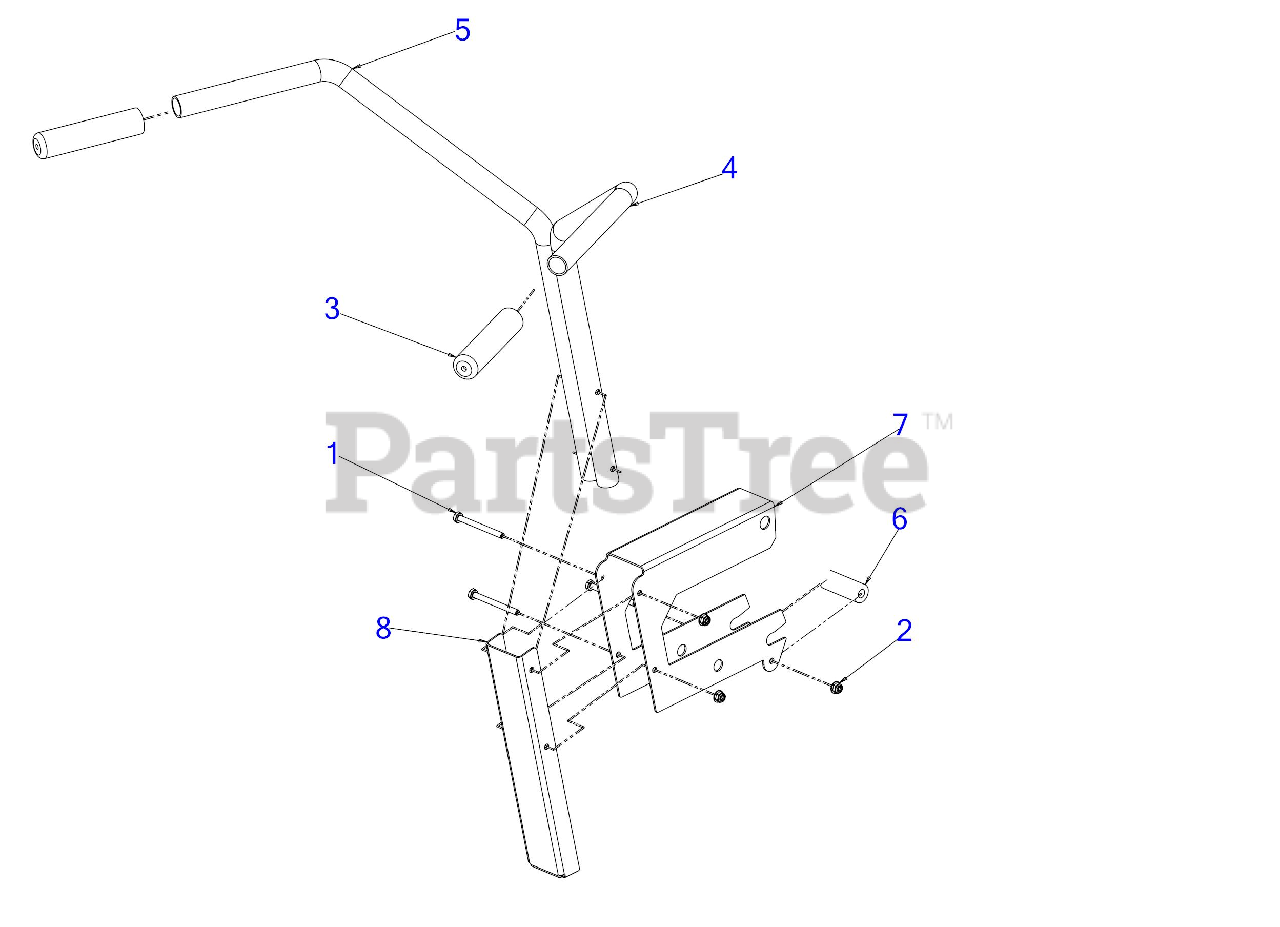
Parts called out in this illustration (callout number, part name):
1	SCREW 1/4-20 x 2.75 GR5
2	FLANGE LOCK NUT
4	HAULER HANDLE (RH)
5	HAULER HANDLE (LH)
6	SPACER .41 x .875 x 2.19
7	HANDLE MOUNT BRACKET
8	HANDLE SUPPORT BRACKET
